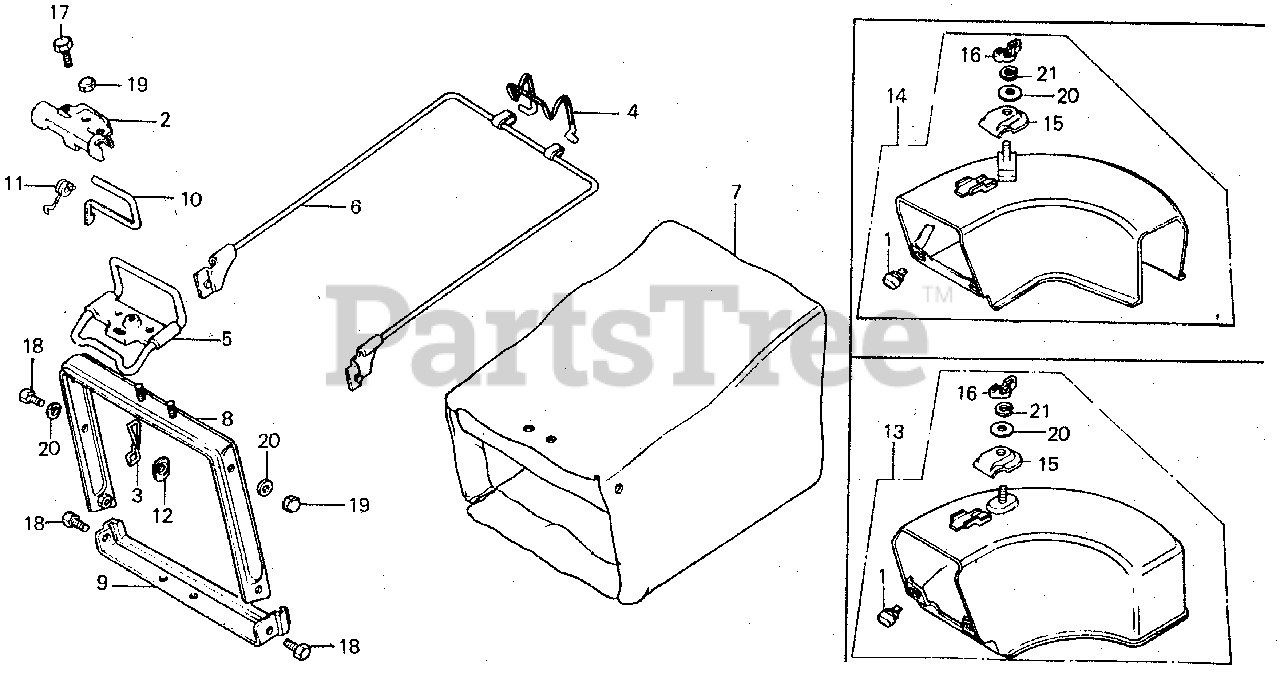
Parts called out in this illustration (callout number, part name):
1	STOPPER, DISCHARGE GUARD
2	PLATE, HINGE BAG (NOT AVAILABLE)
3	HOOK, BAG SET (NOT AVAILABLE)
4	GRIP, GRASS BAG (NOT AVAILABLE)
5	HANDLE, FR. GRASS BAG
6	BAR, GRASS BAG (NOT AVAILABLE)
7	FABRIC, GRASS BAG
8	FRAME A, BAG (NOT AVAILABLE)
9	FRAME B, BAG
10	LEVER, LOCK BAG
11	SPRING, LOCK LEVER RETURN
12	NUT, HOOK HOLDER (NOT AVAILABLE)
14	ADAPTER, DISCHARGE (N/A: SEE COMPONENTS)
15	PLATE, CLAMP
16	NUT, TOOL BOX SETTING
17	BOLT, HEX. (6X8)
18	BOLT, HEX. (6X12)
19	NUT, CAP (6MM)
20	WASHER, PLAIN (6MM)
21	WASHER, SPRING (6MM)
NI	MULCH PLUG (HR21) (NOT AVAILABLE)
